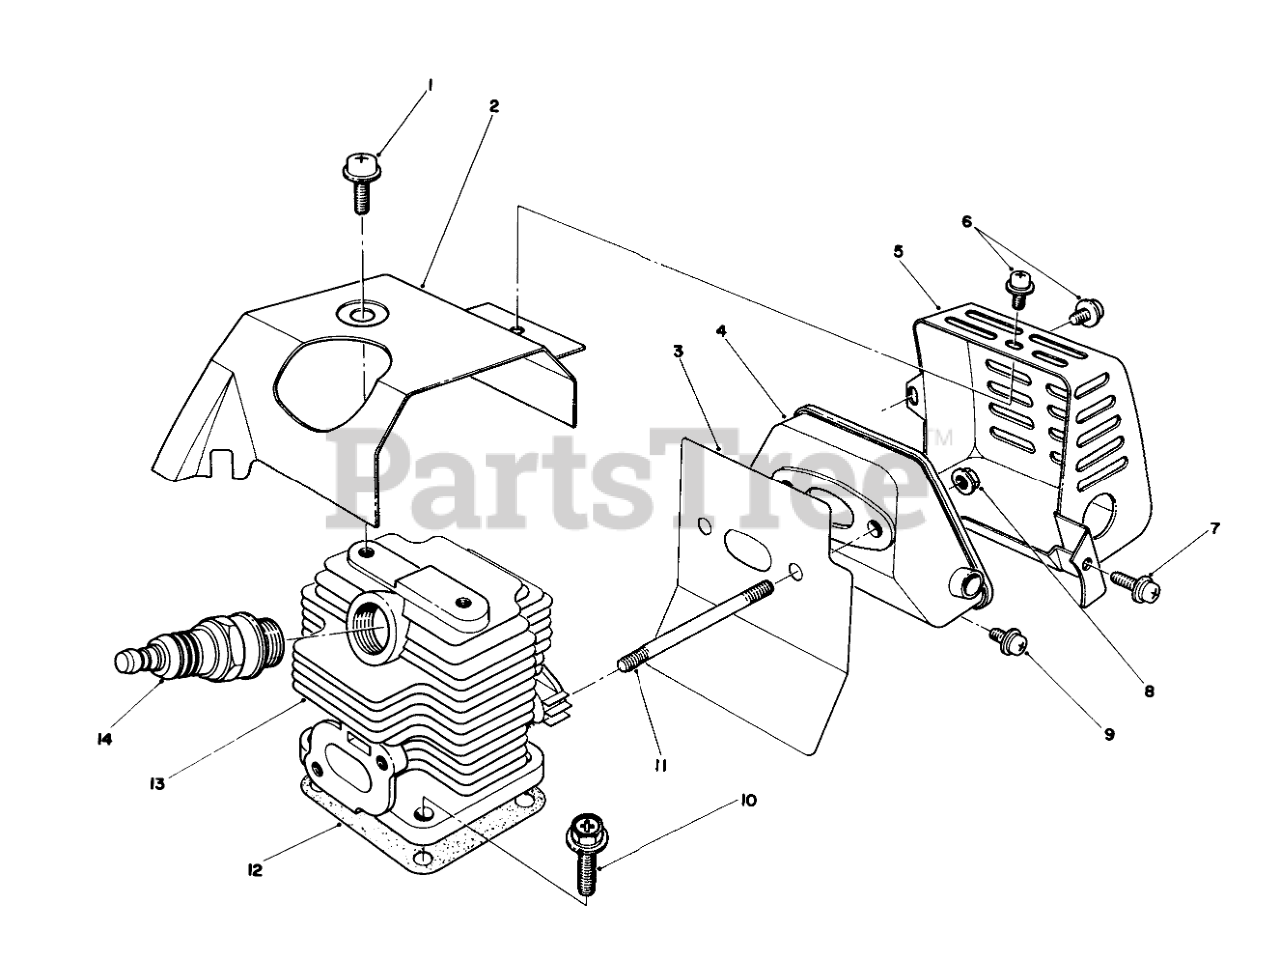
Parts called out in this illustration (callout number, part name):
1	Screw & Dishes
2	CYLINDER COVER
3	Gasket-Muffler
4	MUFFLER
5	COVER, MUFFLER
6	Screw & Washer
7	Screw & Washer
8	NUT, FLANGE
9	Screw & Washer
10	BOLT AND WASHER
11	Bolt-Stud
12	CYLINDER GASKET
13	Cylinder (Incl. Ref. #11)
14	SPARK PLUG (NGK)
